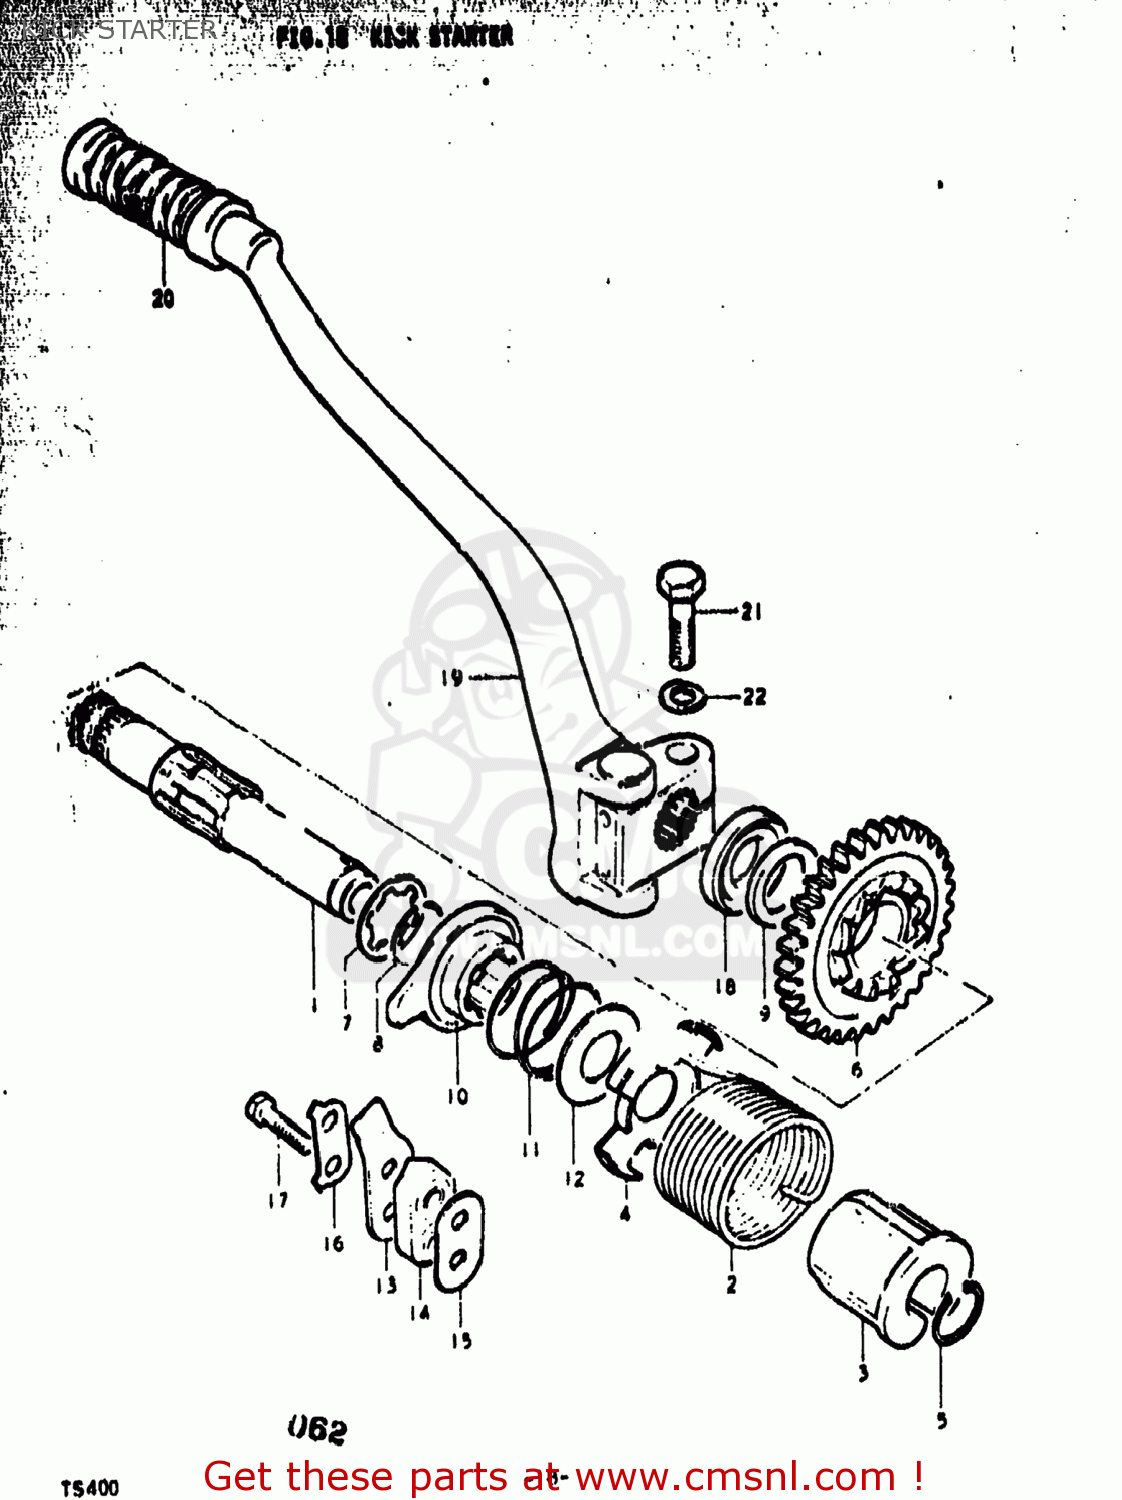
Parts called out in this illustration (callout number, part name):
1	SHAFT,KICK STARTER
2	SPRING
3	GUIDE,KICK SHAFT SPRING
4	HOLDER,KICK SHAFT SPRING
5	CIRCLIP
6	GEAR,KICK STARTER DRIVE
7	WASHER,LOCK
8	CIRCLIP
9	WASHER
10	STARTER,KICK
11	SPRING
12	WASHER
13	GUIDE,KICK STARTER
15	WASHER
16	WASHER
17	BOLT
18	SEAL,OIL(20X37X7)
19	LEVER ASSEMBLY,KICK STARTER
20	RUBBER,KICK STARTER PEDAL
21	BOLT 10X30
22	LOCK WASHER
